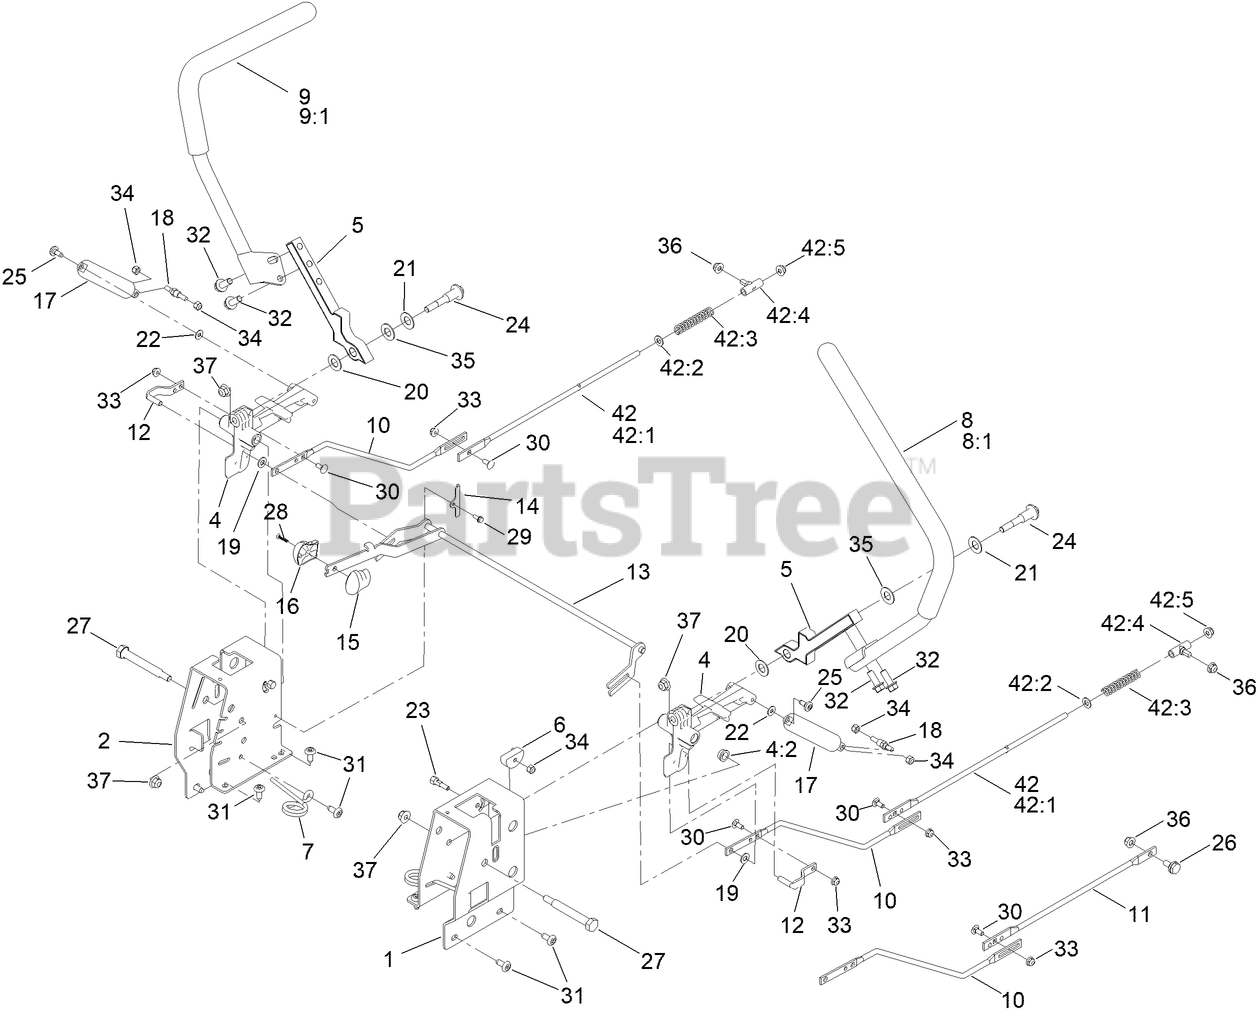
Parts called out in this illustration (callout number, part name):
1	PLATE-CONTROL BOX, LH
2	PLATE-CONTROL BOX, RH
4	ACTUATOR ARM ASM
4:2	BUSHING-FLANGE
5	ARM-CONTROL
6	ECCENTRIC
7	SPRING-TORSION
8	HANDLE-CONTROL, LH
9	HANDLE-CONTROL, RH
10	ROD-HYDRO, FRONT
11	ROD-HYDRO, REAR
12	PIN-ROD, HYDRO
13	SPEED CONTROL ASM
14	PLATE-RETAINER
15	KNOB-RH
16	KNOB-LH
17	DAMPER-NON CAVITATING
18	STUD-DAMPER
19	SPACER-NYLON
20	WASHER-NYLON
21	WASHER-BELLEVILLE
22	WASHER
23	BOLT-PIVOT, ECCENTRIC
24	BOLT-PIVOT
25	SCREW-SHOULDER
26	BOLT-SHOULDER,HFH
27	BOLT-PIVOT
28	SCREW-PPH
29	SCREW-TAPTITE
30	BOLT-CARR
32	SCREW-HHF
33	NUT-HF
34	NUT-HEX
35	WASHER
36	NUT-HF
37	NUT-HF, NI
42	ROD HYDRO ASM
42:1	ROD-HYDRO, REAR
42:2	WASHER-PLAIN
42:3	SPRING-COMPRESSION
42:4	MOUNT-ROD, HYDRO
42:5	NUT-HF
